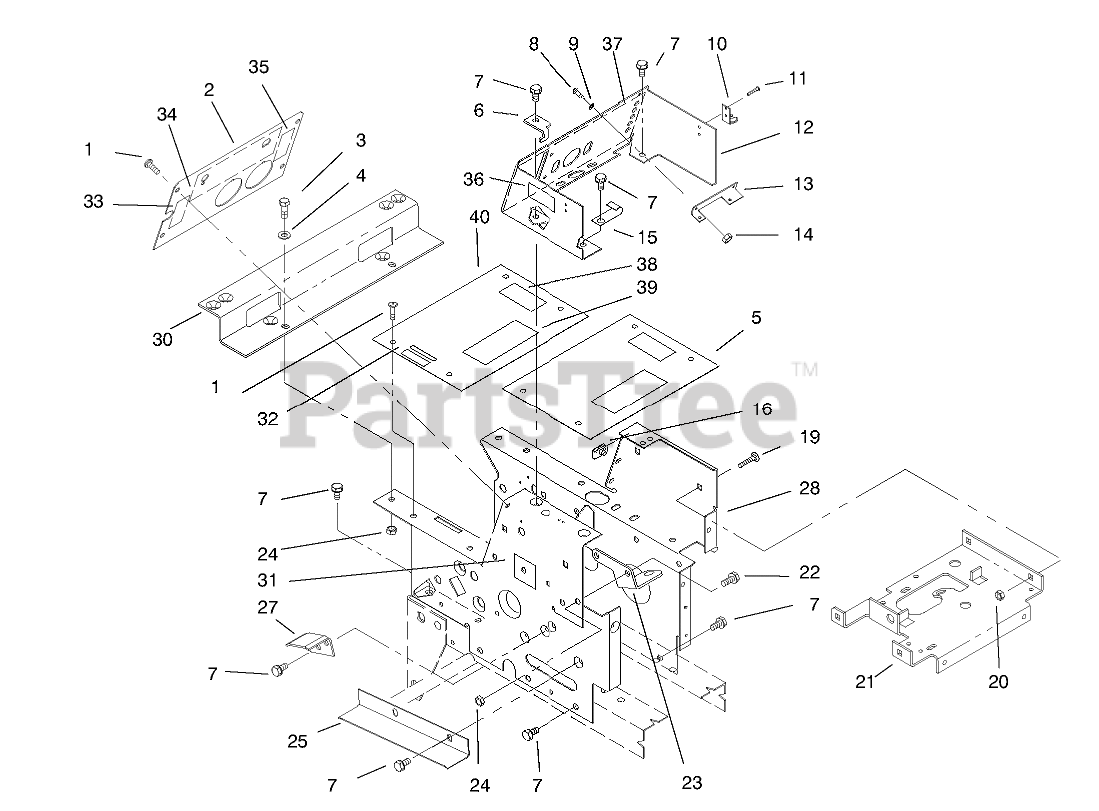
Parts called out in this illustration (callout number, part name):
1	SCREW-PPH
2	PLATE-HOODSTAND (BLACK)
3	SCREW-HH
4	WASHER-PLAIN
6	STOP-PTO
7	Bolt
8	SCREW-PAN
9	Washer-Lock
10	KEEPER-LATCH
11	RIVET-POP
12	Console
13	BRACKET
14	Nut
15	J-CLIP
19	BOLT CARR. 5/16X1/2 BK
20	Nut
21	Bracket-Battery Support
22	SCREW-HH
23	BRKT-LR CNTROL (BLACK)
24	NUT-LOCK, NI
25	Angle-Belt Guard
27	Bracket-Belt
28	Hoodstand
30	Bracket-Fender
31	DECAL - MODEL 314-H
32	DECAL-COLD START
33	DECAL PTO CLUTCH
34	DECAL-BACK PLATE
35	DECAL-CHOKE
36	DECAL ELECT SYSTEM
37	DECAL-DASH
38	DECAL-PARKING BRAKE
39	DECAL-DANGER
40	PLATE SHIFT (BLACK)
